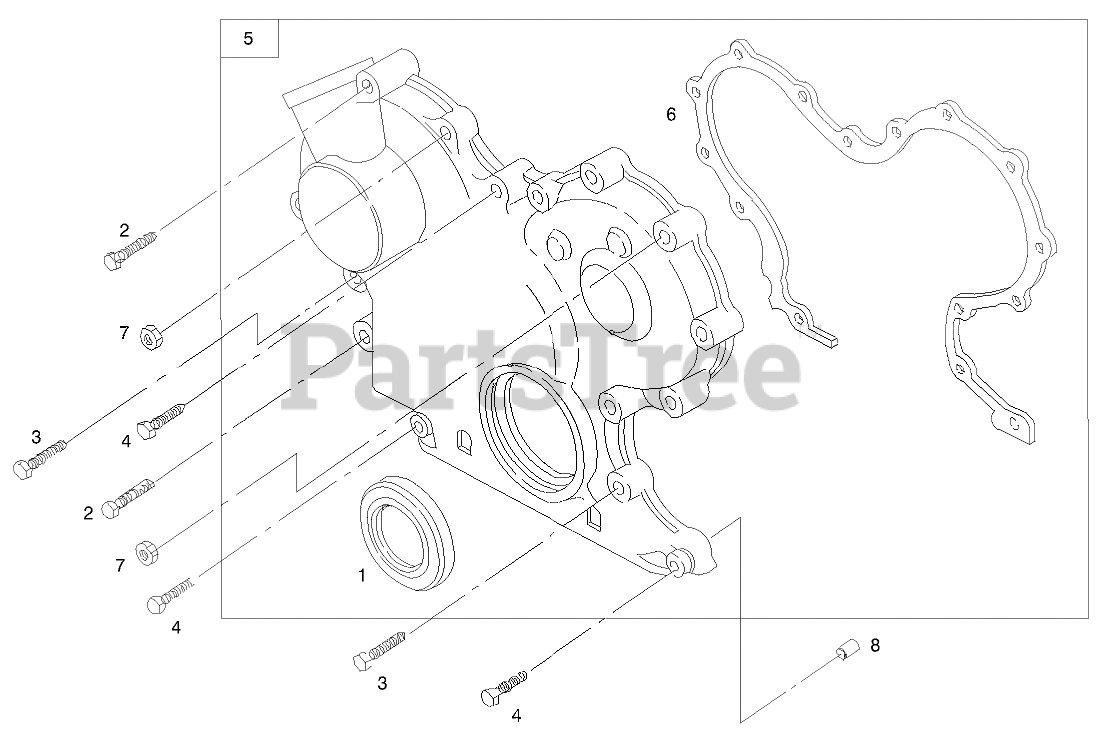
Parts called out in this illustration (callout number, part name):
1	SEAL-OIL
2	SCREW-HEX
3	SCREW-HEX
4	SCREW-HEX
4	NIPPLE ASM
5	GEAR COVER ASM
5	VALVE ASM
6	GASKET-COVER, GEAR
7	NUT-HEX, METRIC
8	PIN-LOCATING
9	GASKET-SET
14	VALVE OVERHAUL KIT
15	SHAFT-GEAR
